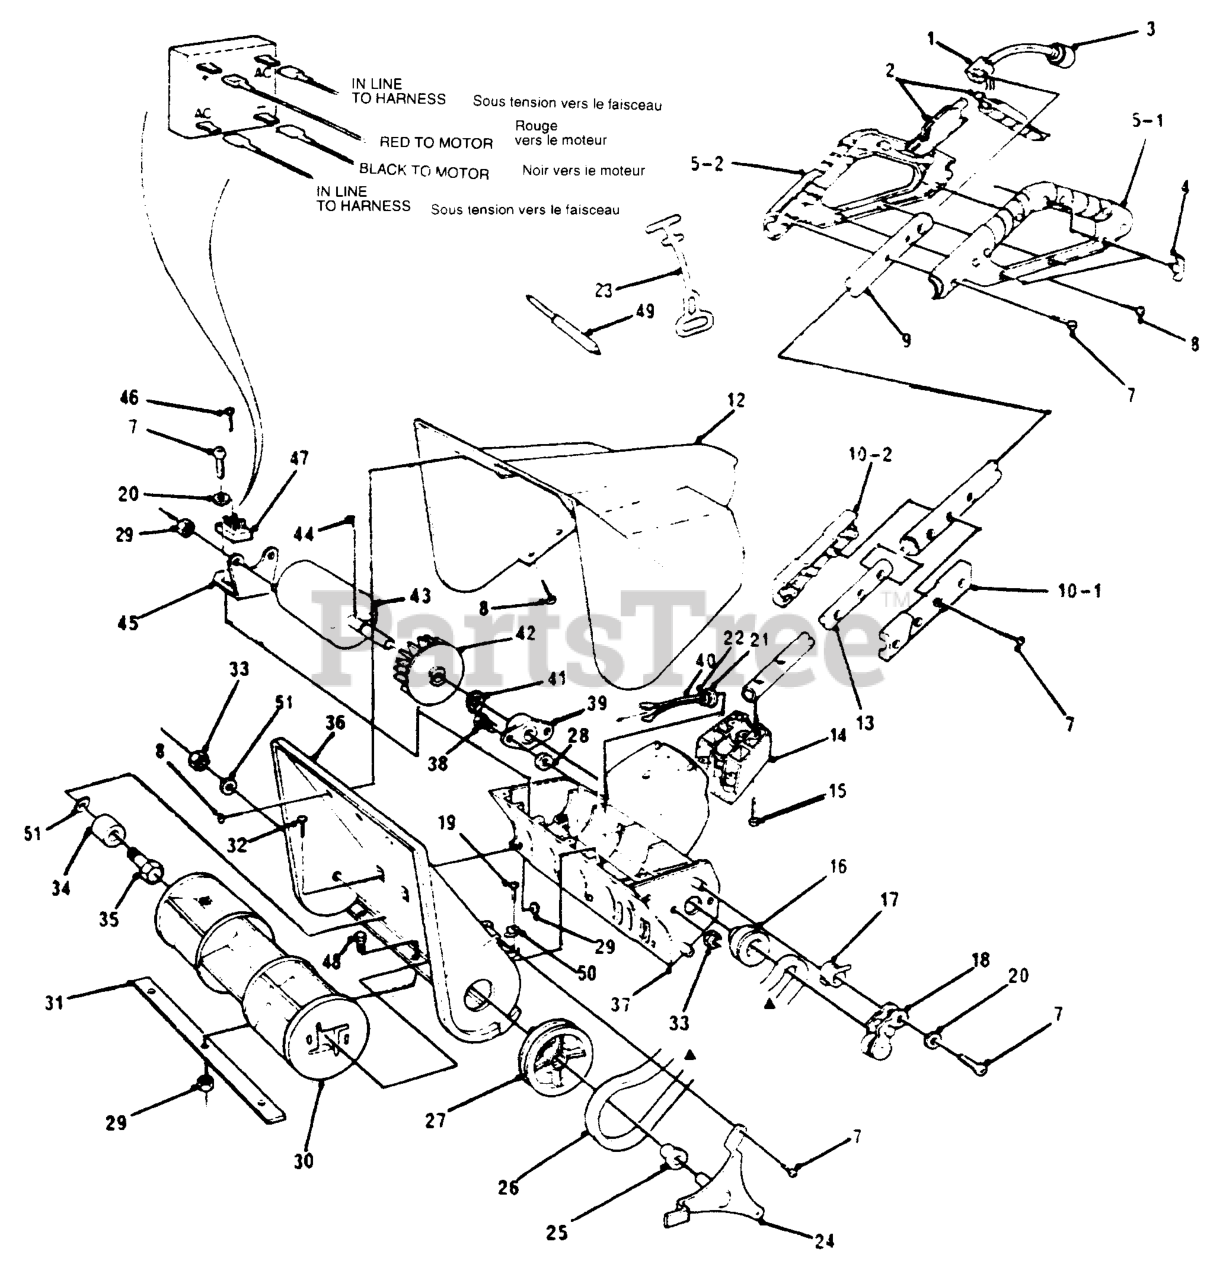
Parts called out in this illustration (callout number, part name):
1	SWITCH, TRIGGER
2	TRIGGER, LEVER 12"
3	LEAD, CONNECTING
4	KEY-DOUBLE NOTCH
5	SET, GRIP TRIGGER L&R 12"
5-1	ORDER SET
5-2	ORDER SET
7	SCREW, #8 X 3/4 POLY
8	SCREW, #8 X.50 POLY
9	TUBE - HANDLE, UPPER
10	SET, GRIP CENTER 12"
10-1	ORDER SET
10-2	ORDER SET
12	HOUSING, UPPER 12"
13	HANDLE, LOWER
14	HOUSING, REAR 12"
15	SCREW, 10-9 X 1.062
16	PULLEY, ENGINE
17	SPRING, TORSION
18	PULLEY, IDLER & BRKT. ASSY
19	SCREW, #8 X1.00
20	WASHER, FLAT #8 SAE
21	CLAMP, HEYCO
22	WASHER, FLAT .505X1.00X.06
23	STRAIN RELIEF, CORD
24	BRACKET, ASSY DRIVE PULLEY
25	BEARING-BRONZE
26	BELT, V 3L DRIVE
27	PULLEY, DRIVEN E12"
28	WASHER, PLASTIC
29	NUT, #10-32 HNYLLK
30	IMPELLER, 12"
31	BLADE, SCRAPER
32	SCREW, 10-32X .50
33	NUT, 1/4-20 REGHEXCTRLK
34	SPACER, IMPELLER
35	SCREW, 1/4-20X1.00
36	HOUSING, IMPEL 12"
37	HOUSING, LOWER 12"
38	SCREW, 1/4-20X .50
39	BEARING, SELF ALIGN
40	WIRE HARNESS, E12"
41	RING, RET E
42	FAN,MOTOR,EXTENDED
43	MOTOR,120V
44	PIN, GROOVED
45	BRACKET, MOTOR MOUNT
46	SCREW, #6-32X .75
47	RECTIFIER, FULL WAVE
48	SCREW, 10-32X .50
49	PROBE, PLASTIC
50	PLUG, RETAINER
51	WASHER, 3/4 X 1/4 X 1/16
